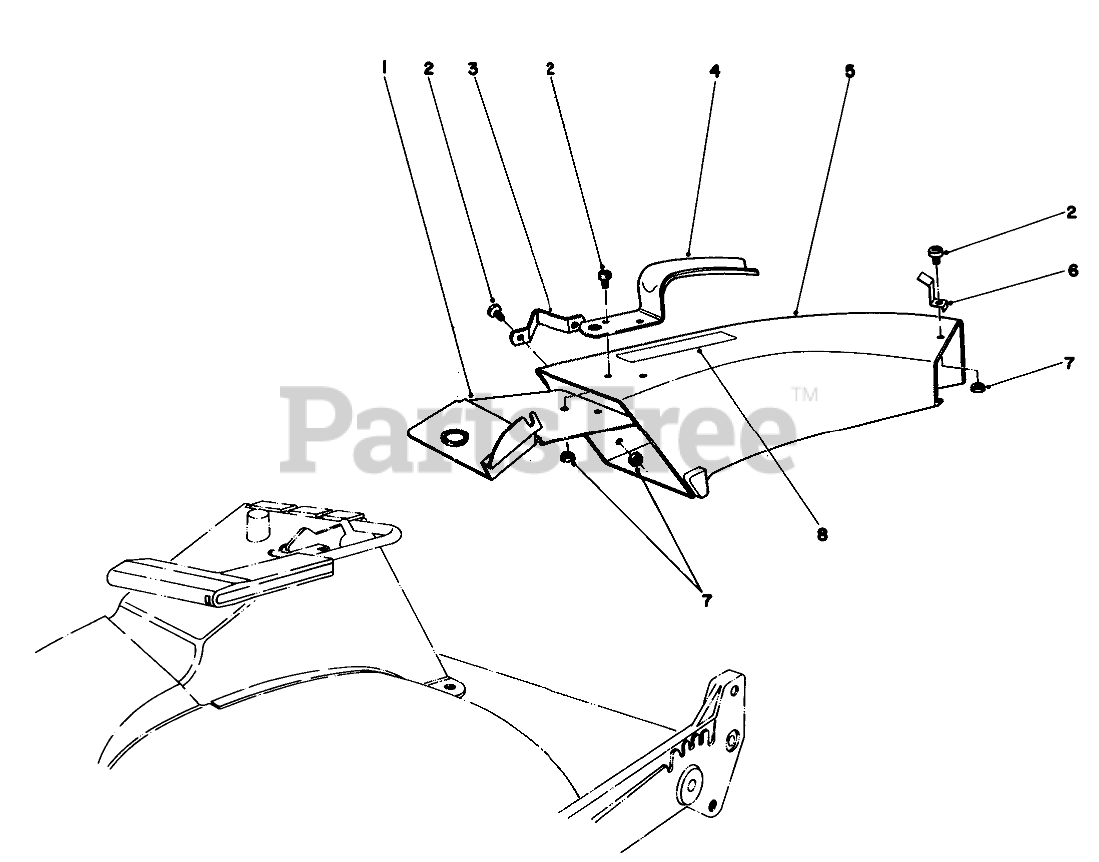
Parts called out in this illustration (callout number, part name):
1	Plate-Discharge Chut
2	10-24 X 5/8 PAN HD MS
3	SIDE BRACKET
4	CHUTE HANDLE
5	Chute-Discharge (Incl. Ref. #8)
7	NUT-LOCK, NI
8	DECAL CAUTION
